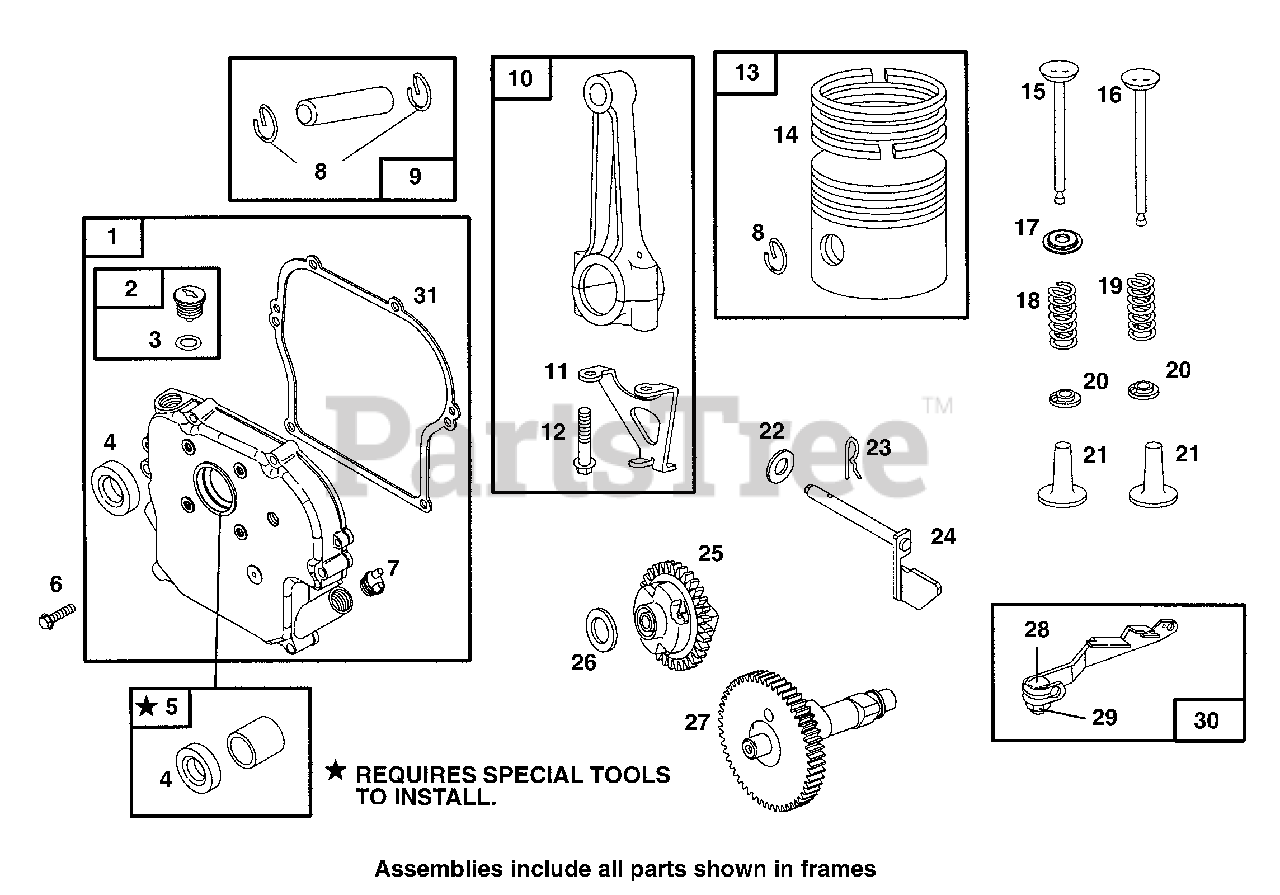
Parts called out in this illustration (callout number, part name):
1	Crankcase Cover
2	Oil Fill Cap
3	Seal-O-Ring
5	Bushing/Seal Kit
6	Hex Screw
7	Oil Fill Cap
8	Piston Pin Lock
9	Piston Pin
10	Connecting Rod
11	Connecting Rod Dipper
12	Connecting Rod Screw
13	Piston Assembly (Standard)
14	Piston Ring Set (Standard)
15	Exhaust Valve
16	Intake Valve
17	Valve Retainer
18	Valve Spring
19	Valve Spring
20	Valve Retainer
21	Valve Tappet
22	Flat Washer
23	Cotter Pin
24	Governor Crank
25	Governor Gear
26	Thrust Washer
28	Carriage Bolt
30	Governor Lever
31	Crankcase Gasket
